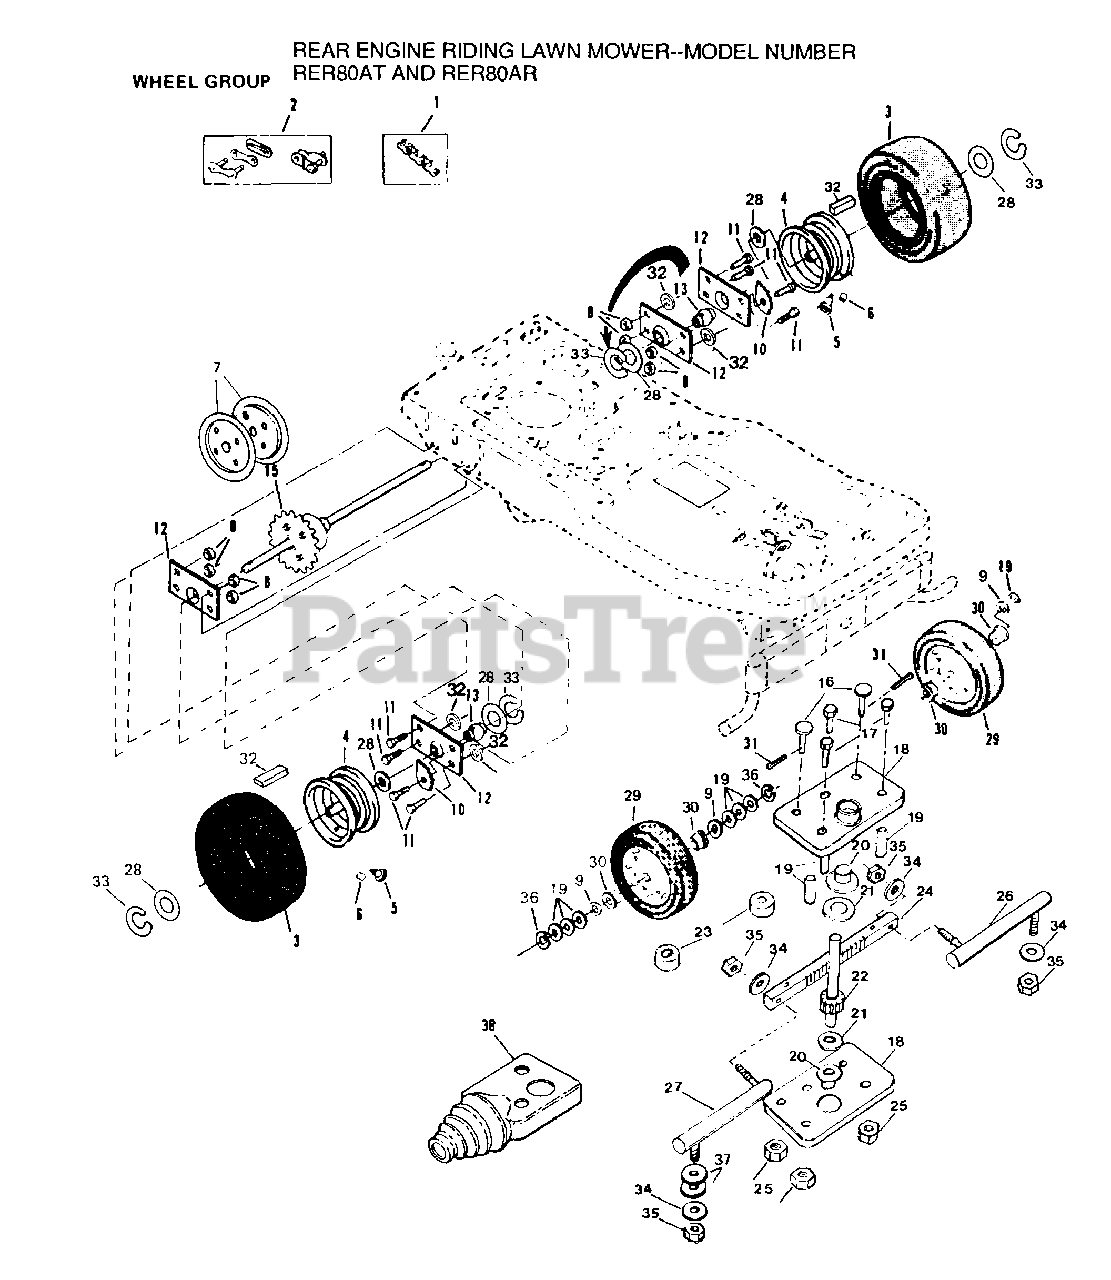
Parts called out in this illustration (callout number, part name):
1	CHAIN#41(82PITCHE
5	VALVE STEM LT
6	VALVE CAP
9	WASHER.21/32X1
12	"CUP, BEARING"
13	"LT, BEARING"
15	DIFFERENTIAL R
16	RIVET - DRILLED
20	NYLON BEARING
27	ROD.TIE.RH.REEN
31	COTTER PIN
33	E-RING LT
